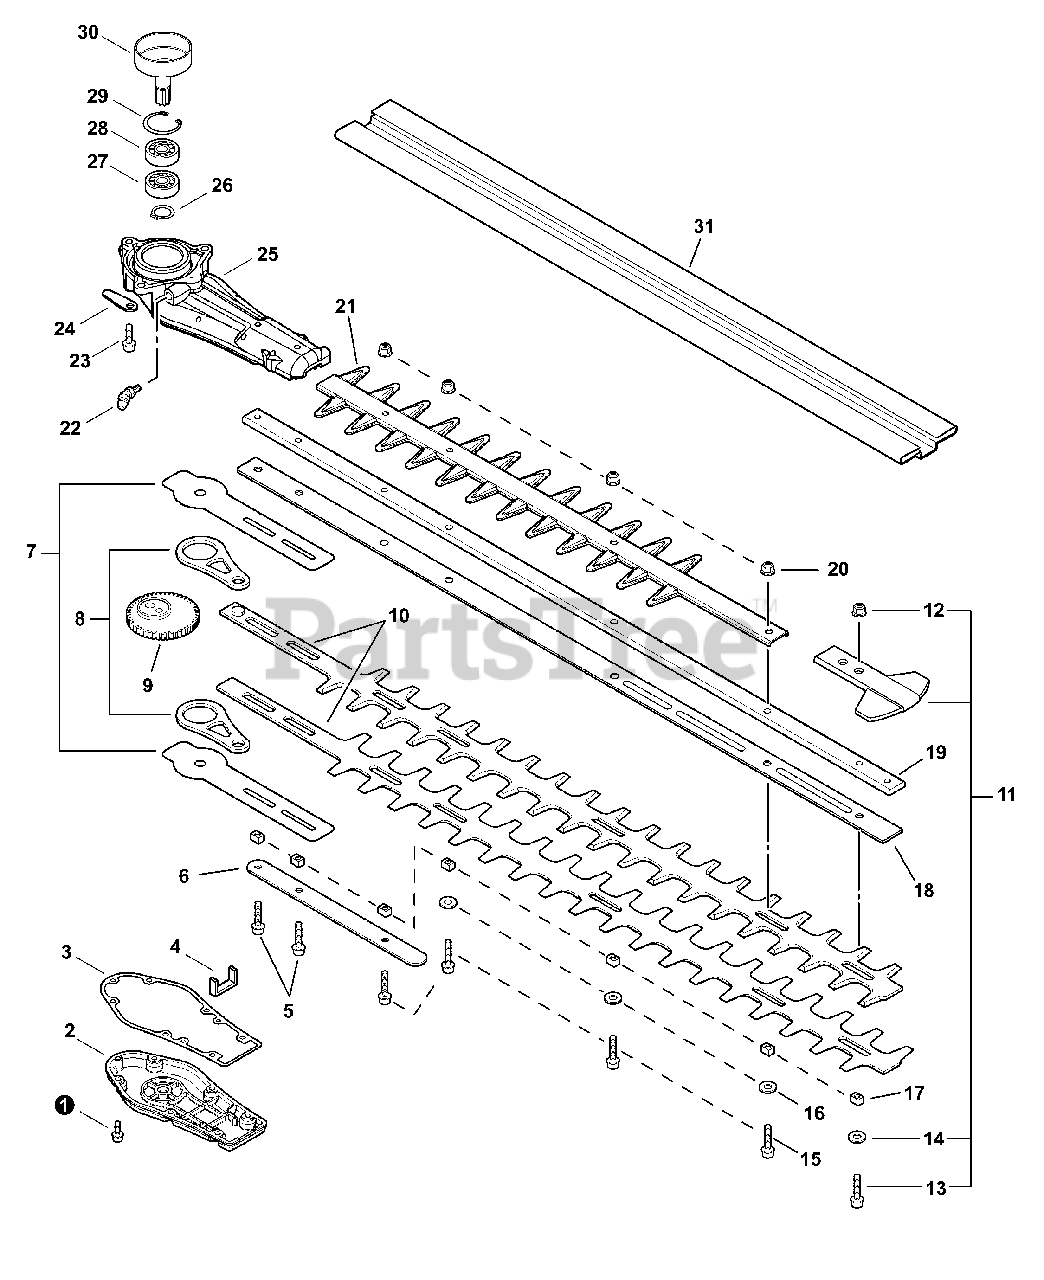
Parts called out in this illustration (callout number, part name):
1	SCREW - 4×16
2	LID, GEAR CASE
3	GASKET, GEAR CASE
5	SCREW - 5×25
6	SUPPORT, BLADE
7	PLATE, WEAR
8	ROD, CONNECTING
9	GEAR, SPUR
10	BLADE, TRIMMER
11	TIP GUARD KIT
12	LOCKNUT - 5
13	SCREW - 5×22
14	WASHER - 6
15	SCREW - 5×22
16	WASHER - 6
17	GUIDE, BLADE
18	SUPPORT, BLADE
19	SUPPORT, BLADE
20	LOCKNUT - 5
22	FITTING, GREASE
23	SCREW - 6×20
25	CASE, GEAR
26	RING, RETAINING - 14
27	BEARING, BALL - 6202
28	BEARING, BALL - 6202
29	RING, RETAINING - 35
30	DRUM, CLUTCH
31	COVER, BLADE - 24" (60cm)
